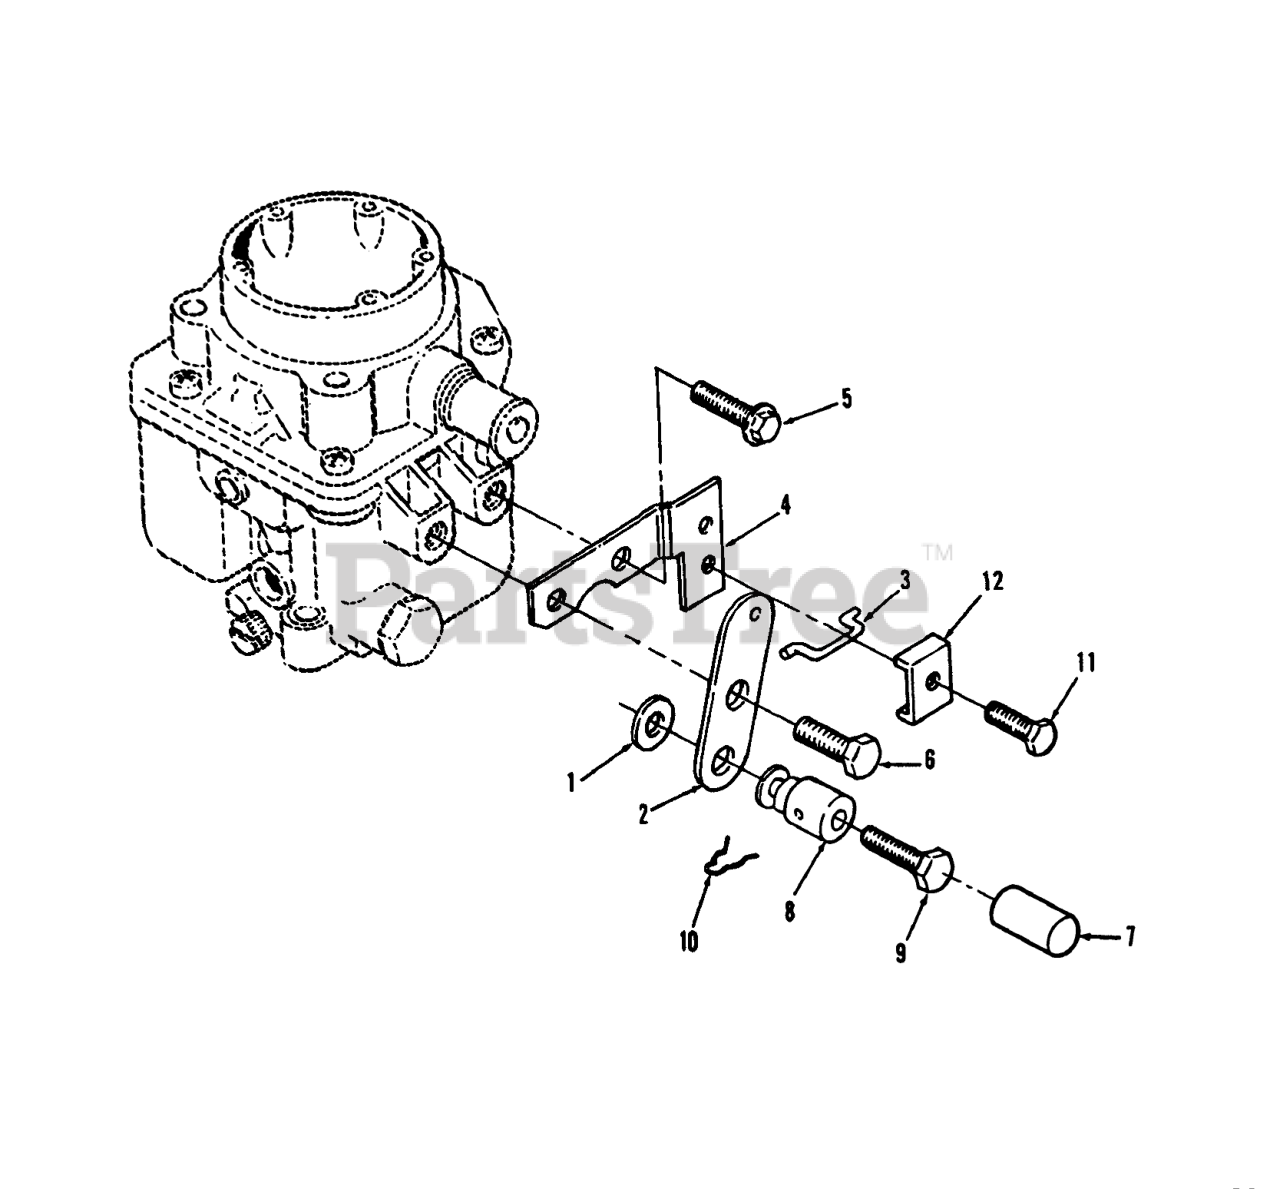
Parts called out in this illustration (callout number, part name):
1	Washer
2	SWIVEL-CHOKE
3	LINK-CHOKE
4	BRACKET
5	Bolt
6	MACHINE SCREW
8	SWIVEL
9	Bolt
10	PIN-COTTER
11	Bolt
